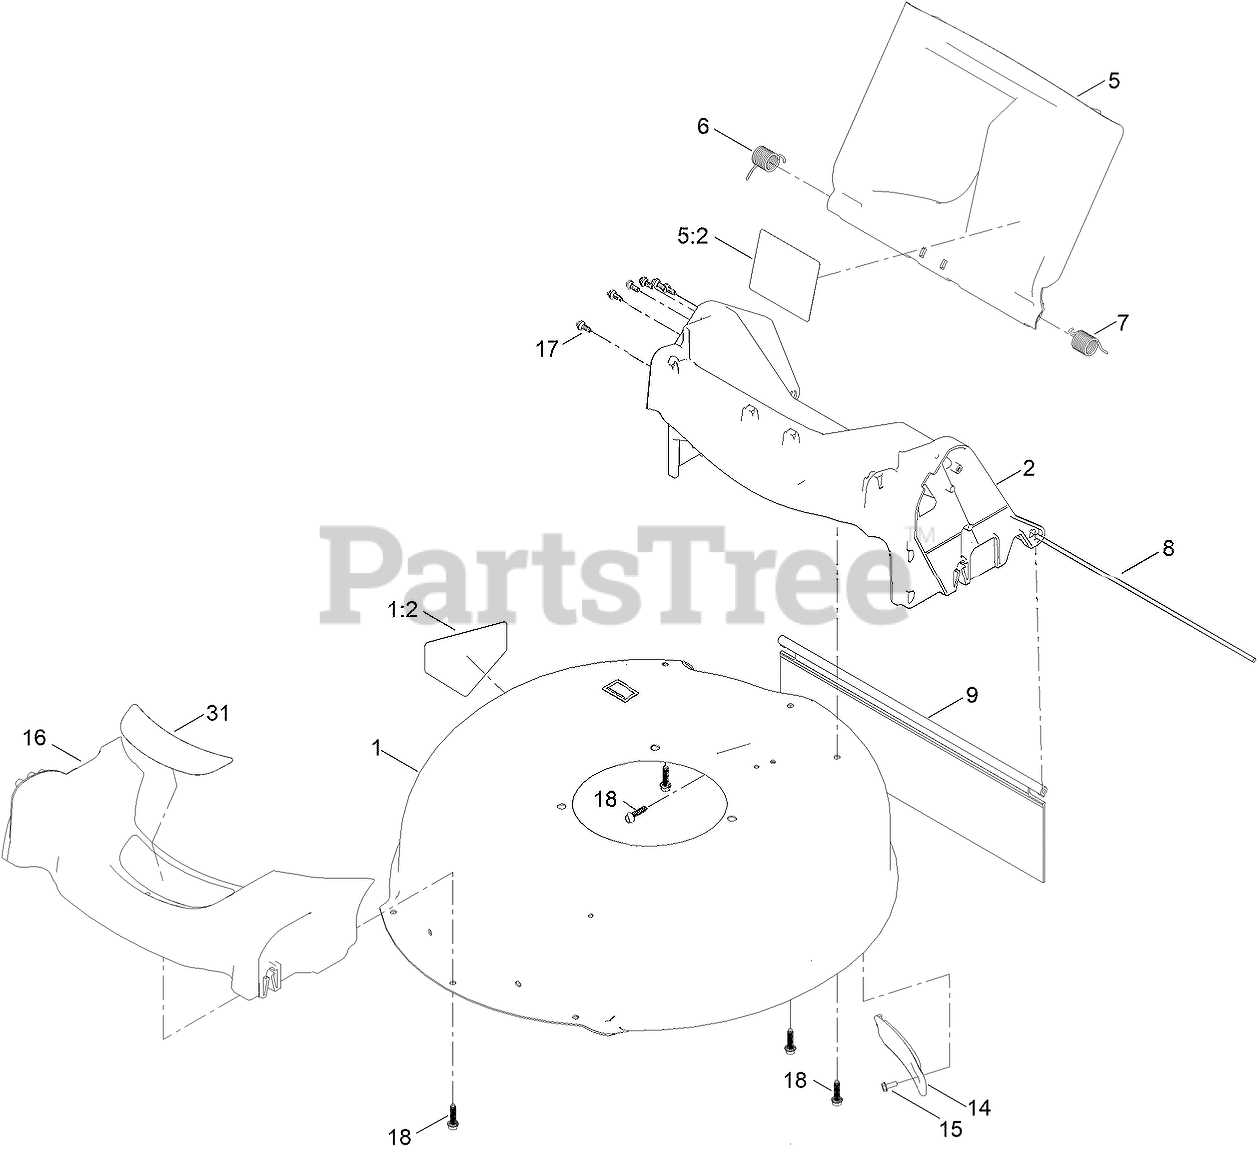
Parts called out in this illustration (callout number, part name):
1	HOUSING ASM
1:2	DECAL-DANGER
2	CHUTE ASM
5	REAR DEFLECTOR ASM
5:2	DECAL-WARNING
6	SPRING-TORSION
7	SPRING-TORSION
8	ROD-DOOR
9	SHIELD-TRAILING
14	COVER-BELT
15	SCREW-TAPTITE
16	BUMPER
18	SCREW-FLANGE, PLASTIC
31	DECAL-DECK
